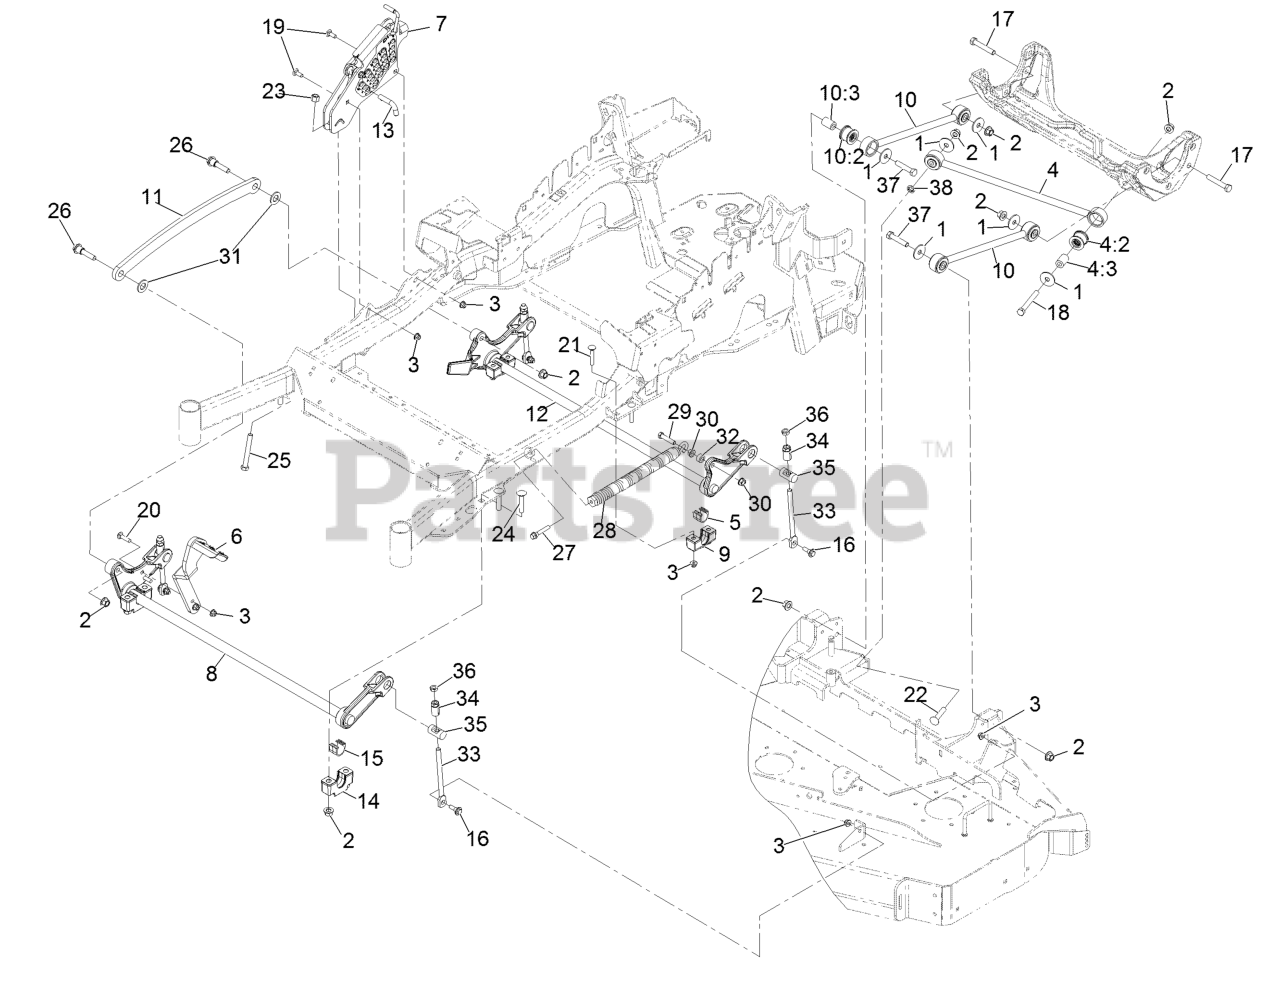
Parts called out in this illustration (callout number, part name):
2	Nut-Lock 1/2-13
3	Nut-Nyloc 3/8-16 Flg
4	Panhard Rod ASM
4:2	Bushing-Suspension, Rubber
5	Bearing-Cross Shaft, Rear
6	Lever-Foot
7	HOC ASM
8	Decklift-Front
9	Support-Cross Shaft, Bearing Rear
10	Deck Strut ASM
10:2	Bushing-Suspension, Rubber
11	Link-Lift, Deck
12	Lift-Deck, Rear
13	Pin-HOC
14	Support-Cross Shaft, Bearing
15	Bearing-Cross Shaft, Front
16	Screw-Hex Flange 3/8-16 X .80
17	Screw-HH 1/2-13 X 3
18	Screw-HH 1/2-13 X 4
19	Bolt-Carriage 3/8-16 X 1
20	Bolt-Carriage 3/8-16 X 1 1/2
21	Bolt-Carriage 3/8-16 X 2 1/4
22	Bolt-Carriage 1/2-13 X 2 1/2
23	Nut-Nyloc 1/2-13
24	Bolt-Carriage 1/2-13 X 2 1/2 Spl Neck
25	Bolt-HH 1/2-13 X 4 Tap
26	Screw-Hex Flange 1/2-13 X 1.90
27	Screw-Shcs 3/8-16 X 2.212
28	Spring-Extension
29	Screw-HH 7/16-14 X 2
30	Nut-Whizlock 7/16-14
31	Washer-3/4 SAE
33	Link-Adjuster, Deck Lift
34	Adjuster-Lift, Deck
35	Trunnion
36	Nut-Jam 1/2-13
37	Screw-HH 1/2-13 X 2 1/2
38	Nut-Push
